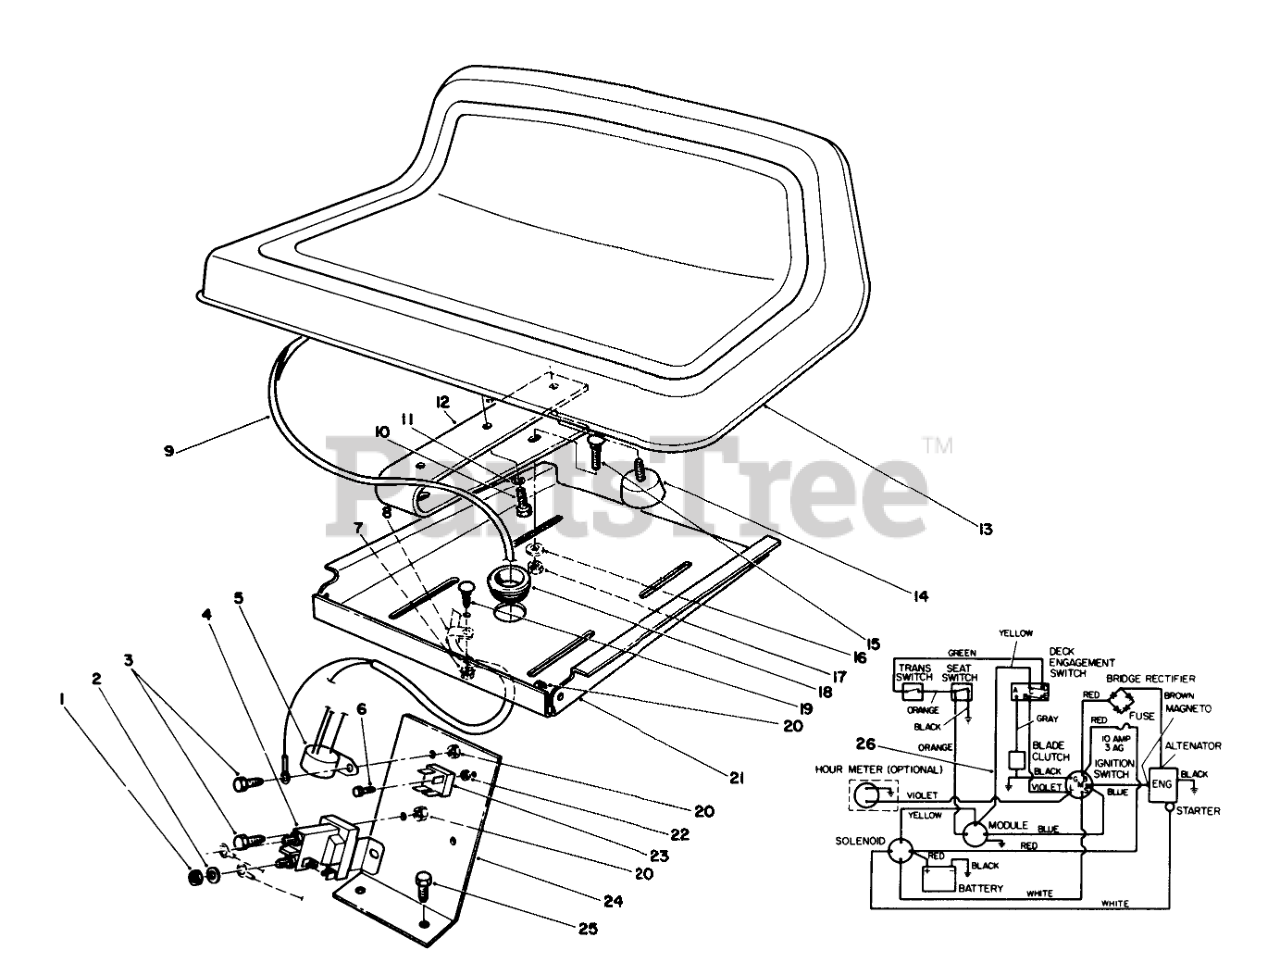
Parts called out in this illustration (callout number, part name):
1	NUT-JAM
2	WASHER-LOCK
3	SCREW-HH
4	SOLENOID
5	MODULE BRIGGS
6	SCREW-HWH
7	NUT-KEPS
8	CLIP-CLOSED, INSULATED
9	SWITCH-SEAT
10	SCREW-HH
11	WASHER-LOCK
12	Spring Seat
14	BUMPER-RUBBER
15	BOLT-CARR
16	WASHER-PLAIN
17	NUT-LOCK, NI
18	GROMMET
19	SCREW-CARR
20	NUT-LOCK, NI
21	SEAT PAN R
22	NUT-LOCK, NI
23	RECTIFIER-BRIDGE
24	ELEC COMPONENT PANEL B
25	SCREW-HH
26	WIRE HARNESS - 12 HP
